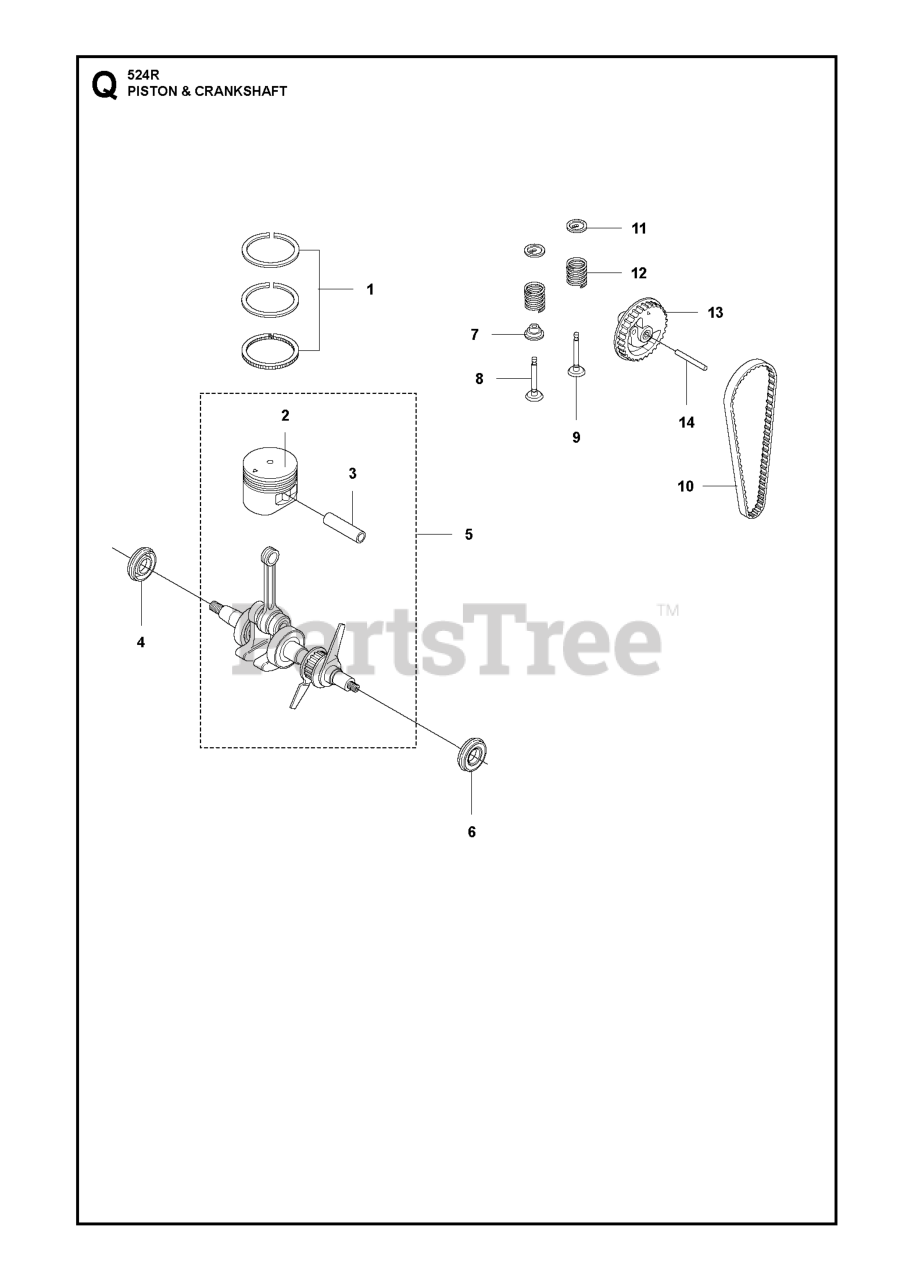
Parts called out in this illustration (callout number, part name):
1	PISTON RING
3	PISTON BOLT
4	SEALING RING
5	CRANKSHAFT
6	SEALING RING
